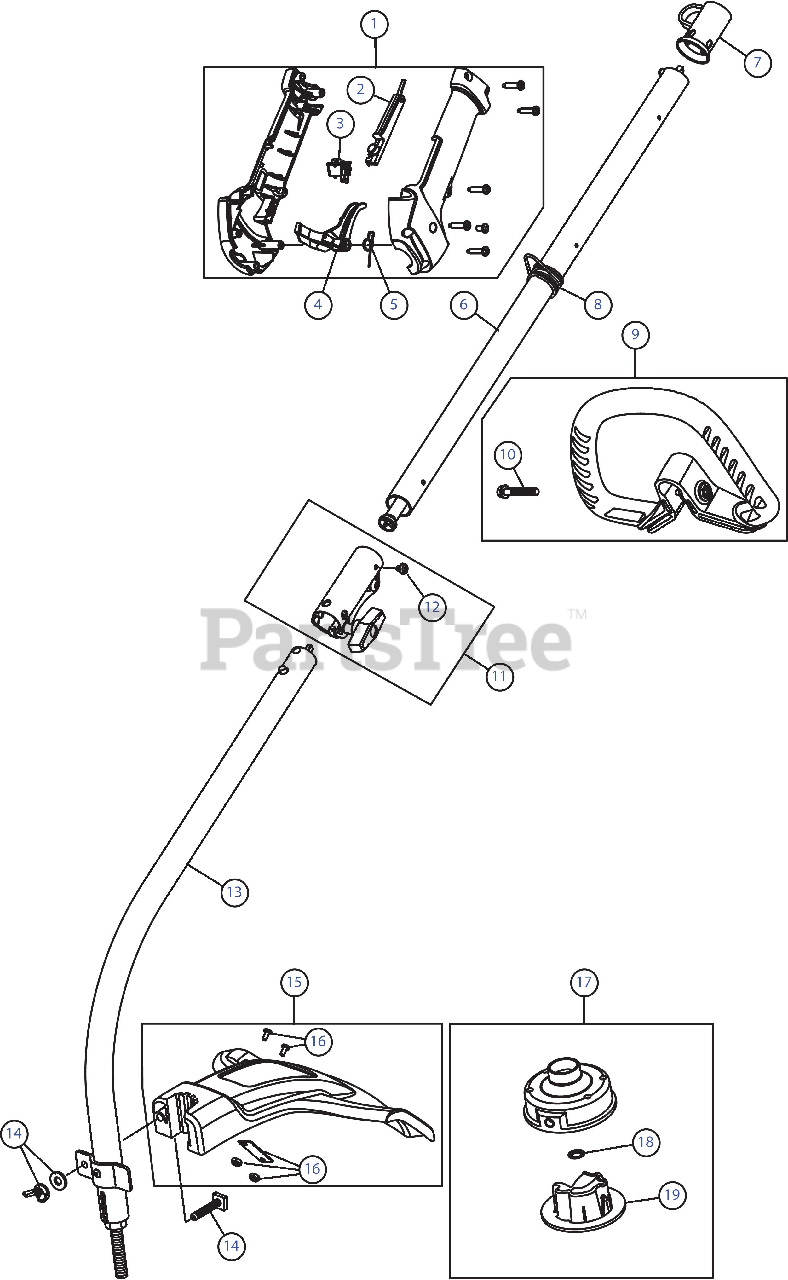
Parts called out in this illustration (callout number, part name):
1	Throttle Housing Assembly (includes 2 - 5)
2	Throttle Trigger Lock-Out
3	Trigger Switch Assembly
4	Throttle Trigger Spring
5	Throttle Trigger
6	Upper Drive Shaft Assembly
7	Hanger
8	Shoulder Strap Clip
9	D-Handle Assembly (includes 10)
11	Split Boom Coupler (includes 12)
12	Coupler Anti-Rotation Screw
13	Lower Drive Shaft Housing
14	Shield Mount Hardware
15	Shield Assembly (includes 16)
16	Blade Assembly
17	Cutting Head Assembly (includes 18 & 19)
18	Push Nut
19	Cutting Head Cap
